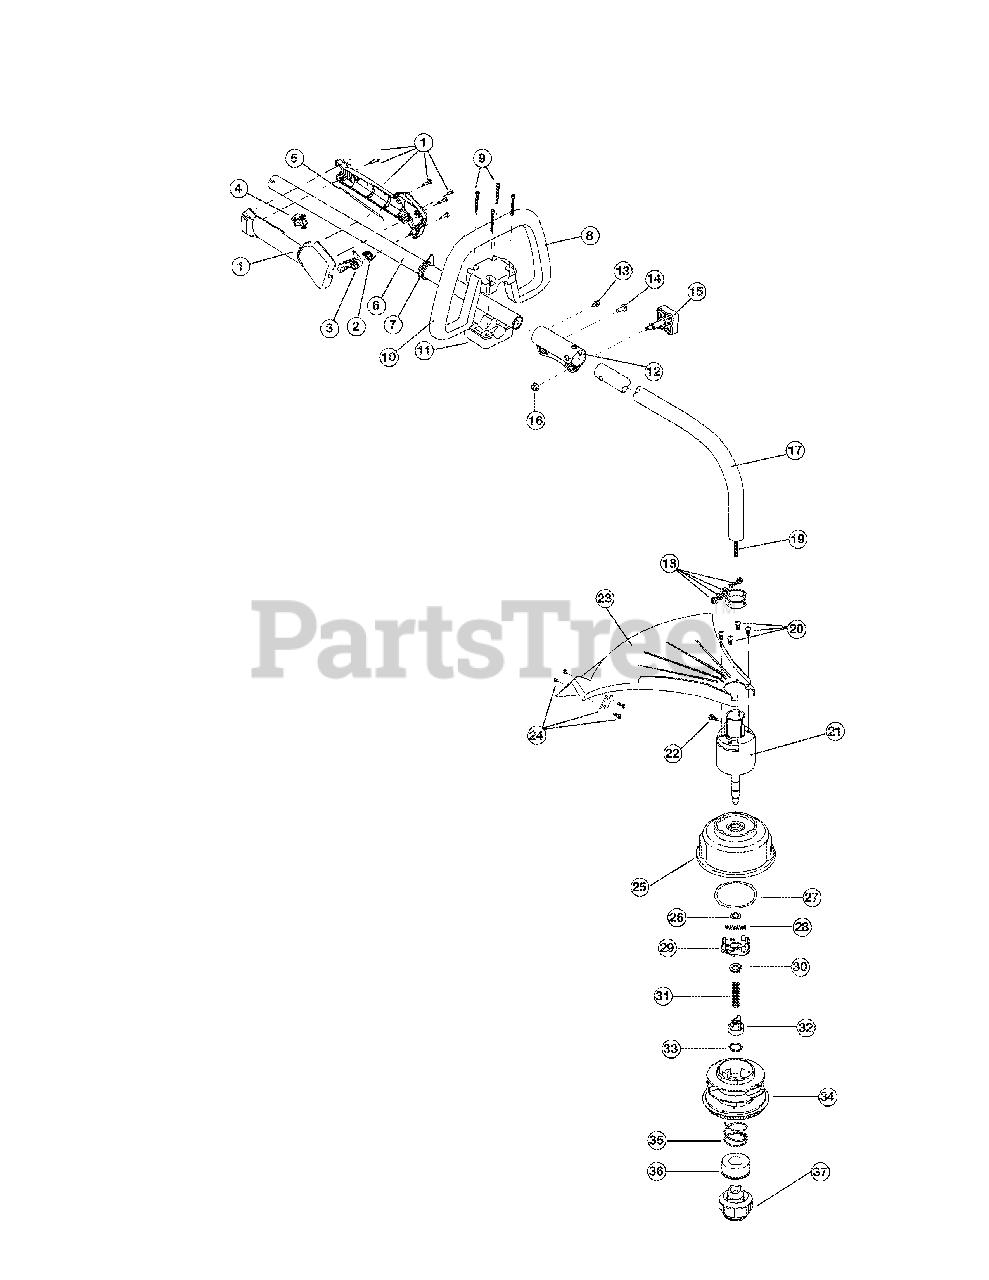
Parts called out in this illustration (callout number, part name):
1	Throttle Housing Assembly (includes 2-4)
2	Throttle Trigger Spring
3	Throttle Trigger
5	Throttle Cable Assembly
6	Upper Drive Shaft Housing Assembly
7	Harness Clip
8	Deluxe D-Handle Assembly (includes 9-10)
10	Deluxe D-Handle
11	Bottom Clamp
12	Split boom Coupler (includes 13-16)
15	Adjustment Knob (includes 16)
16	Knob Retaining Nut
17	Lower Drive Shaft Housing Assembly
18	Lower Clamp Assembly (includes 22)
19	Lower Flexible Drive Shaft
20	Shield Mounting Screw
21	Bushing Housing Assembly
22	Anti-Rotation Screw
23	Shield Assembly (includes 24)
24	Blade Assembly
25	Outer Spool Assembly (includes 26)
27	Thrust Washer
28	Small Spring
34	Inner Reel
35	Large Spring
37	Bump Head Knob Assembly (includes 35 & 36)
